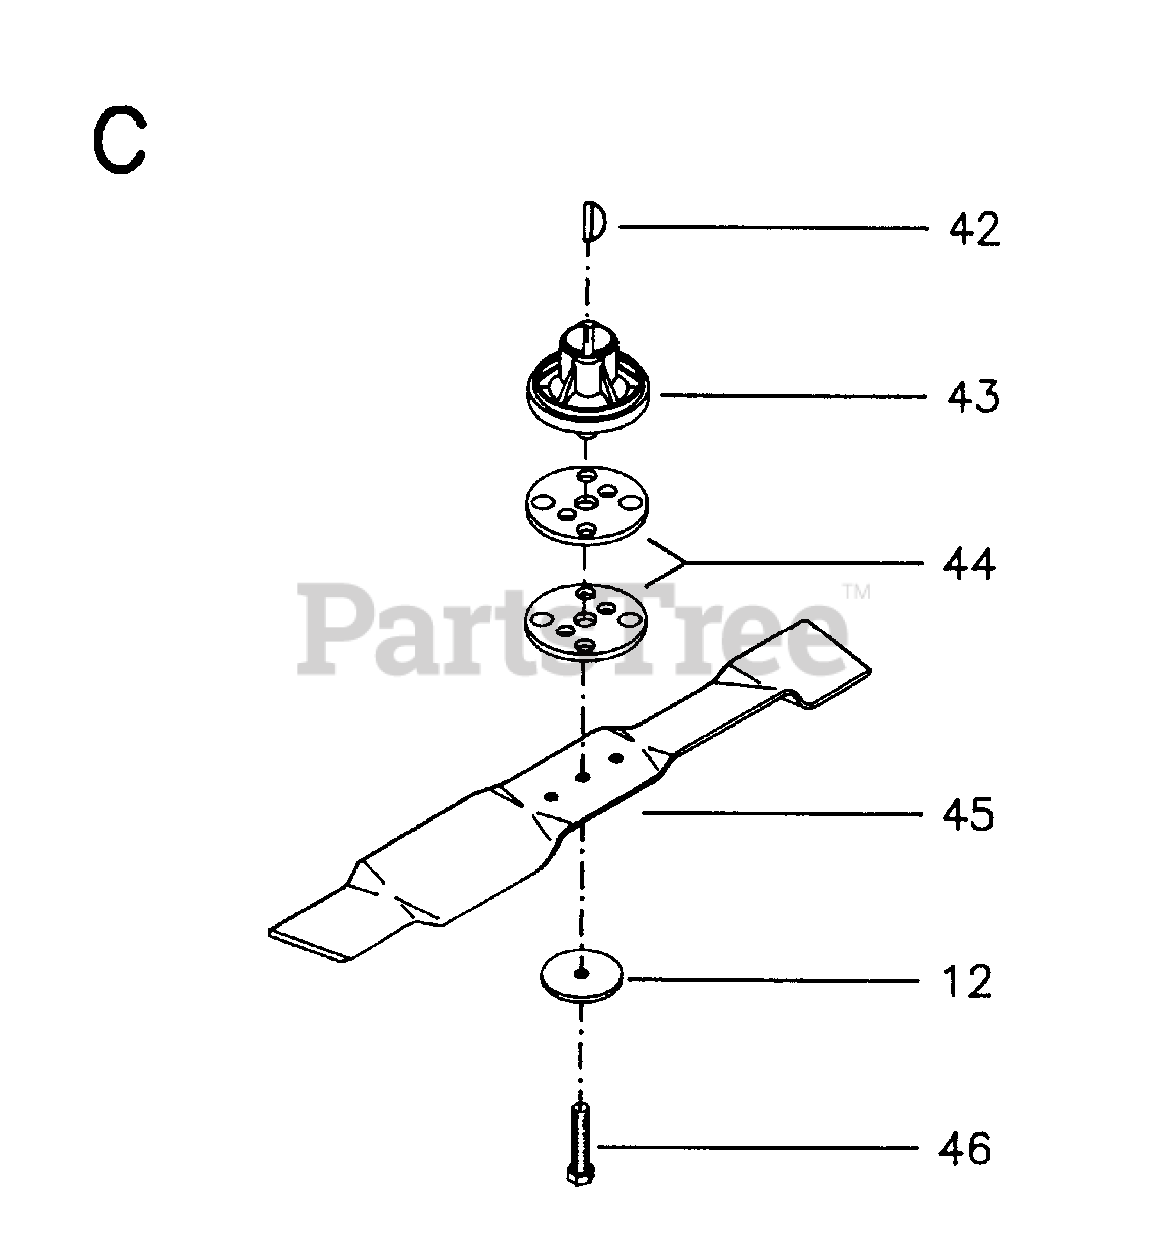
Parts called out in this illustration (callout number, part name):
42	WOODRUFF KEY
43	BLADE ADAPTER
44	STEEL PLATE ADAPTER
